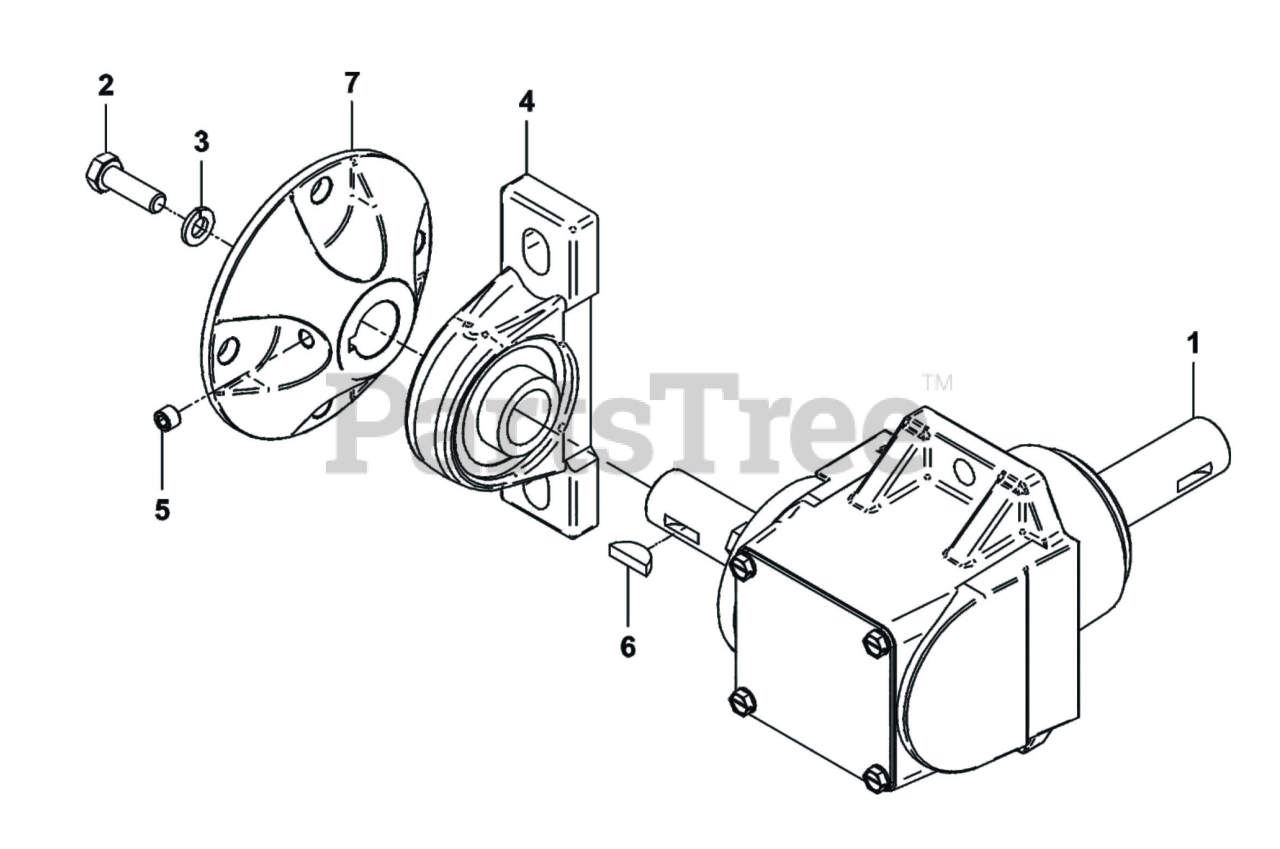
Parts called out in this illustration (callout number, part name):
2	SCREW 5/16"-24 GR8
3	LOCK WASHER 5/16"
4	PILLOW BLOCK BEARING 7/8"
5	SCREW-SET 5/16-18
6	WOODRUFF KEY #9
7	CLUTCH FLANGE ASSEMBLY
